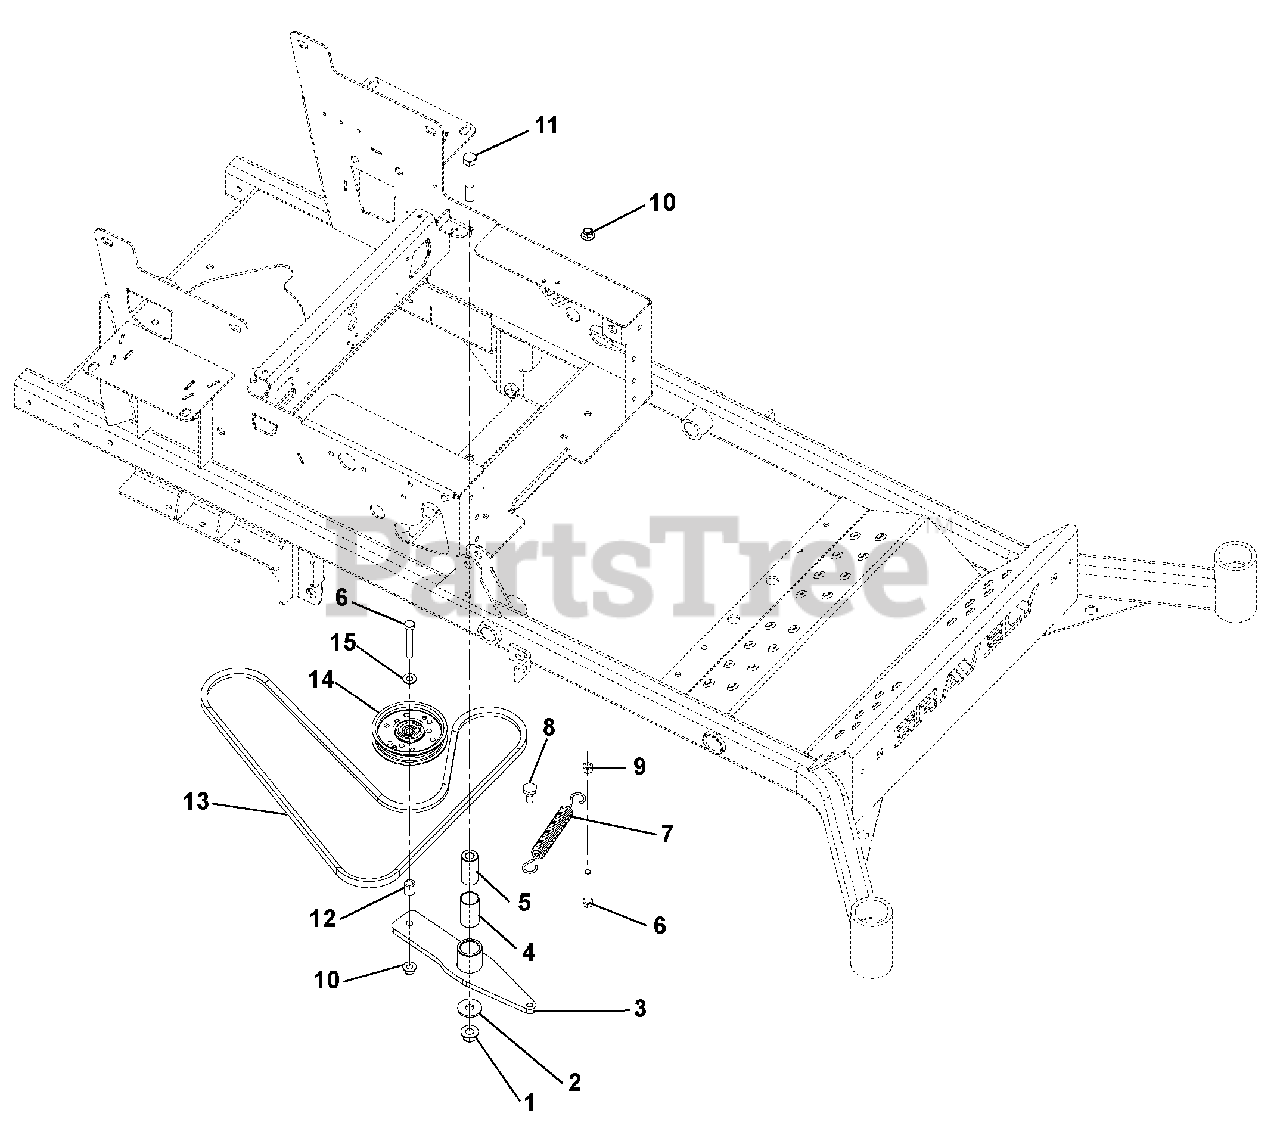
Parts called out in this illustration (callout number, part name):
1	Nut, .50-13 Nyloc Flange
2	Washer, Flat Steel .511 x 1.441 x .125
3	Weldment, Hydro Drive Idler Arm
4	Bushing, 1.00 x 1.125 x 1.936
5	Bushing, Spacer .505/.500 x .999/.996 x 2.05/2.03 Promaster
6	Bolt, Hex .38-16 x 2.50 Grade 5
7	Spring, Extension
8	Bolt, Shoulder EP .38-16 x .30 Hex
9	Nut, Hex .38-16
10	Nut, .38-16 Nyloc Flange
11	Bolt, Hex .50-13 x 3.25 Grade 5
12	Bushing, Sleeve .407 x .625 x .750
13	Belt, A 69.26 Raw Cogged
14	Idler, Flat 4.00X.38
15	Washer, Flat-Steel .406 x .812 x .065
